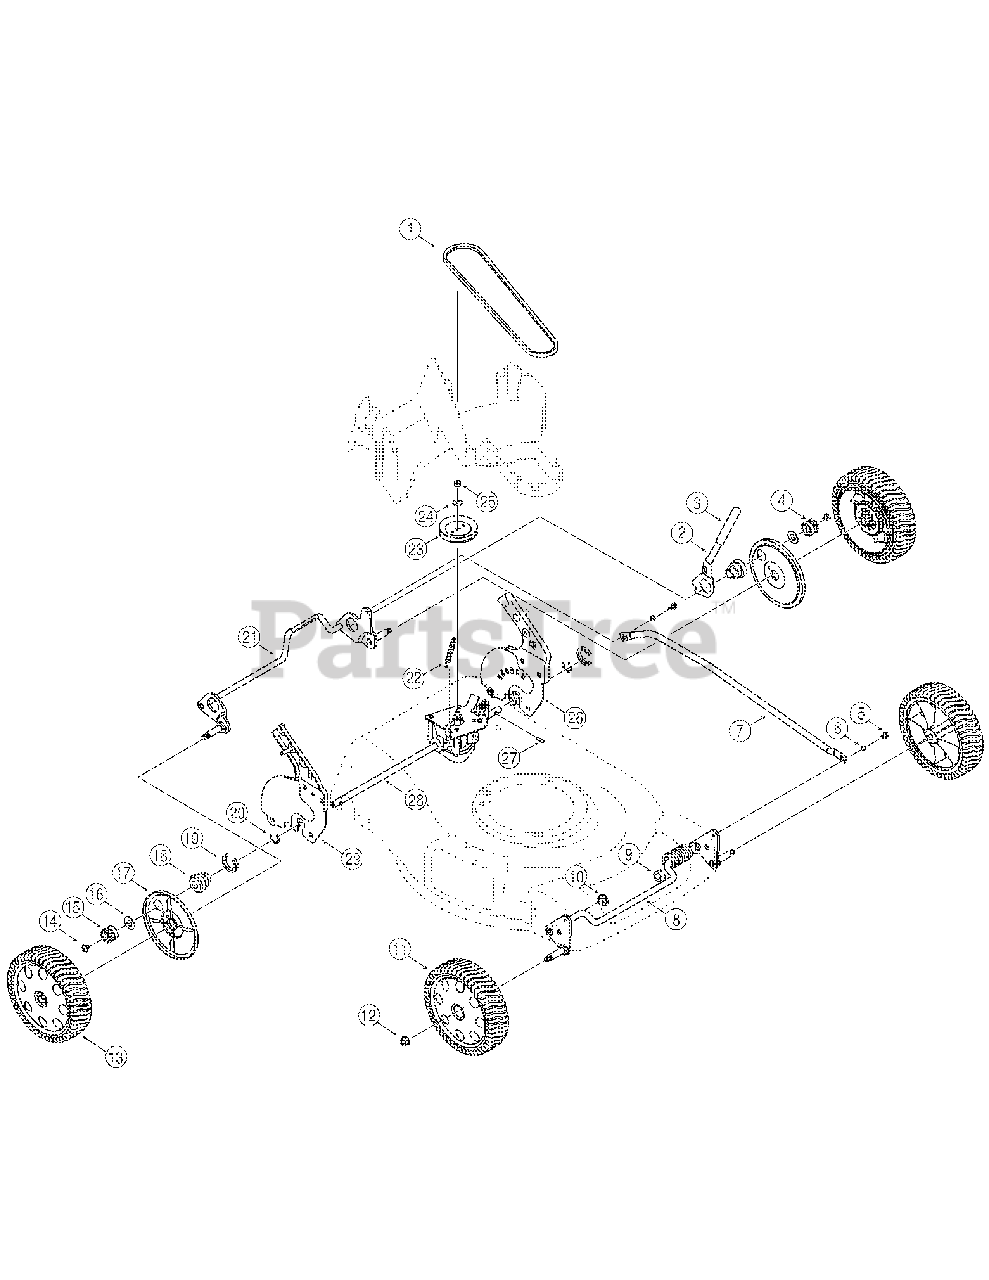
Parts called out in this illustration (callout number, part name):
1	V-Belt
2	Spring Lever
3	Foam Grip
4	Spur Gear, 14T - LH
5	TT Screw, 1/4-20 x 0.50
6	Spacer
9	Clip Spacer
10	Split Hex Flange Bearing
11	Front Wheel
12	Flange Lock Nut, 3/8-16
13	Rear Wheel
14	Screw, 1/4-20 x .39
15	Spur Gear, 14T - RH
16	Flat Washer
17	Wheel Dust Cover
18	Transmission Bearing Support
19	Clip Spacer
20	Retaining Ring .875
22	Extension Spring
23	Pulley, 3.36 OD
24	Bell Washer, .375 x .870 x .063
25	Hex Lock Nut, 5/16-24
27	Dowel Pin
28	Transmission Assembly
